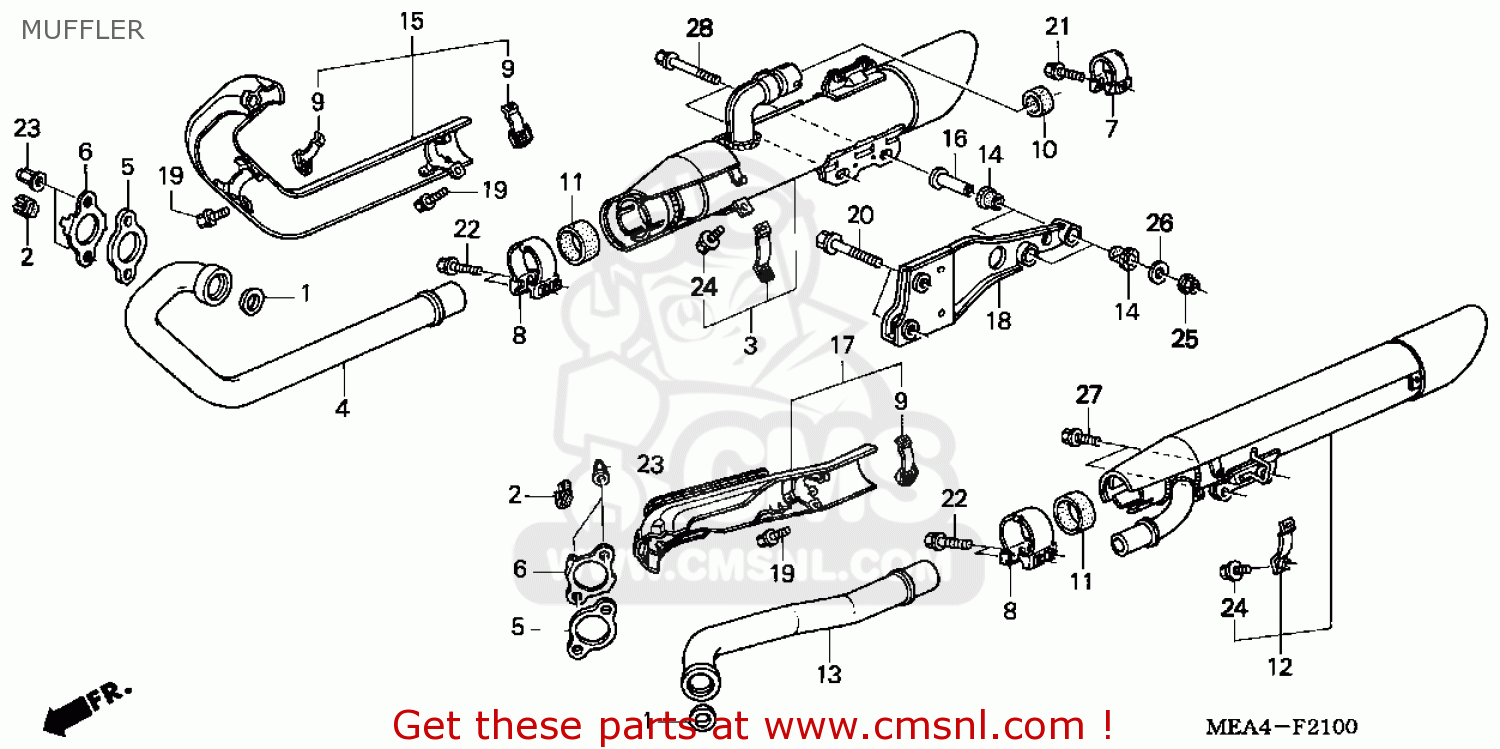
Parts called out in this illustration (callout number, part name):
1	GASKET,EXH PIPE (NAS)
2	RUBBER,PROTECTOR
3	MUFFLER COMP,FR
4	PIPE,FR.EXHAUST
5	JOINT,EXH.PIPE
6	HOLDER,EXPI COVER
7	BAND,L EXH PIPE
8	BAND,MUFFLER
9	BAND,RR EXH PIPE
10	PACKING,MUFFLER (NAS)
11	PACKING,MUFFLER (NAS)
12	MUFF.ASSY RR.EXH.
13	PIPE,RR.EXHAUST
14	RUBBER,MUFFLER MO
15	COVER FR.EXH.PIPE
16	COLLAR,MUFF MOUNT
17	COVER RR.EXH.PIPE
18	BRKT,MUFFLER
19	BOLT,SOCKET,6X16
20	BOLT,FLG.10X51
21	BOLT,FLANGE,8X32
22	BOLT,FLANGE,8X35
23	NUT,CAP,8MM
24	BOLT WASH.,6X12
25	NUT,FLANGE,8MM
26	WASHER,PLAIN,8MM
27	BOLT,FLANGE,8X20
28	BOLT,FLANGE,8X50
